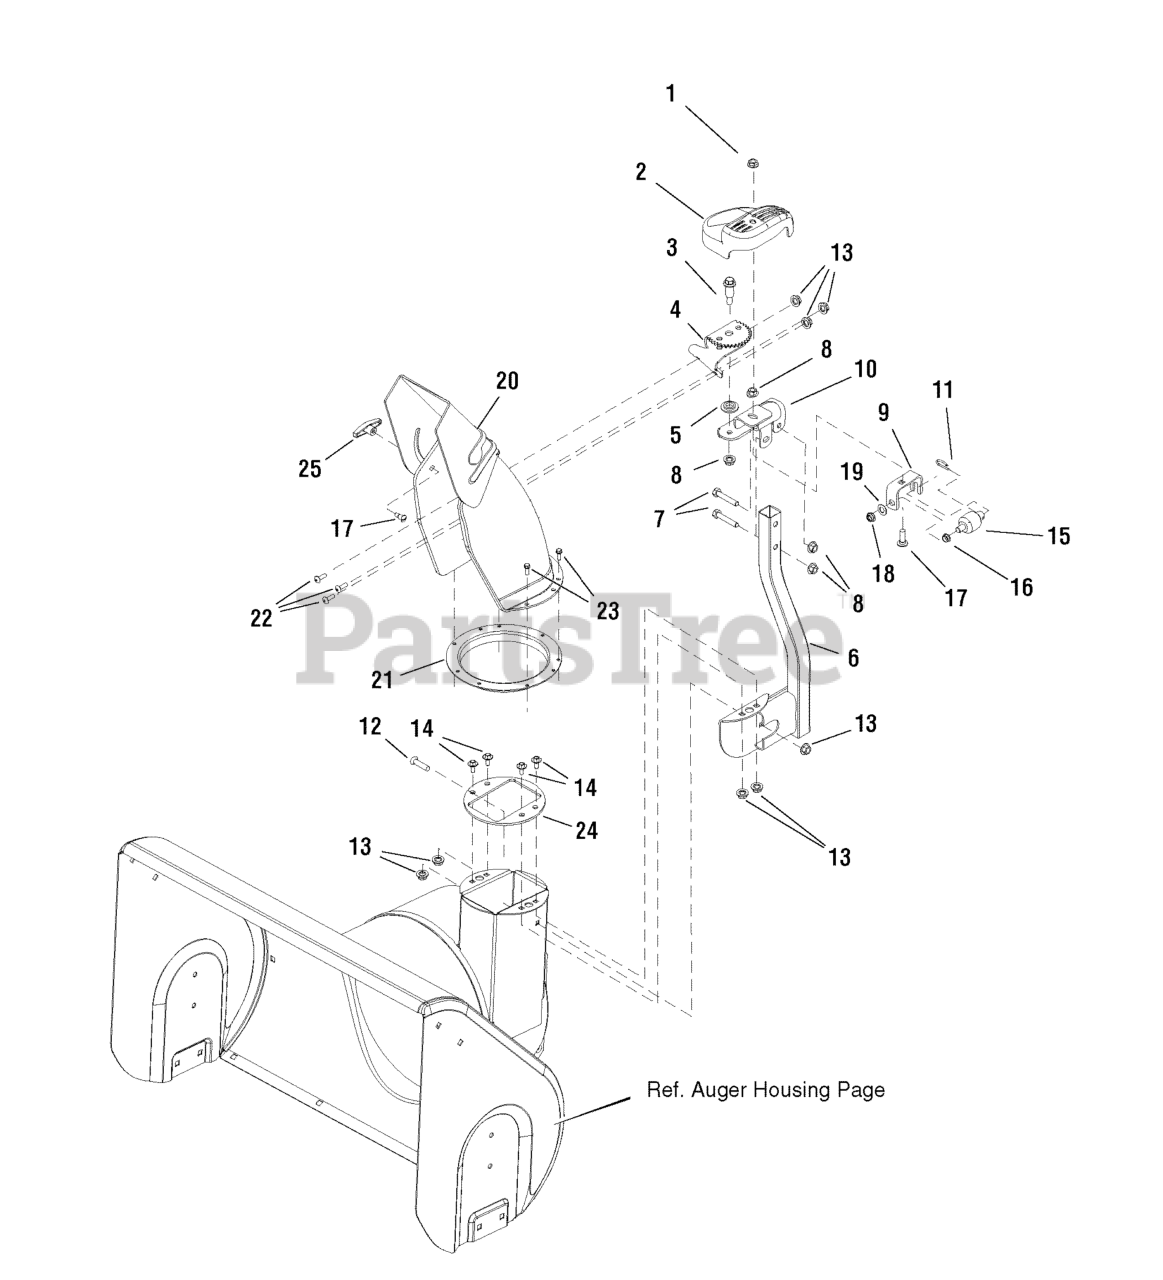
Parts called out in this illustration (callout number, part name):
1	NUT, Hex Flange 5/16-18 Two Way Lock
2	COVER, Gears
3	BOLT, Shoulder 5/16-18 G5
4	GEAR & SUPPORT ASSEMBLY, Chute
5	WASHER, Powdered Metal
6	CHUTE SUPPORT ASSEMBLY
7	SCREW, Hex Head Cap, 5/16-18 x 1 3/4
8	NUT, Hex KEPS 5/16-18 Conical Washer
9	SUPPORT, Worm "U" 10GA
10	SUPPORT, Gear & Chute 10GA
11	PIN, Hair Chute Gear
12	BOLT, CARRIAGE 0.25-20 x 0.75
13	NUT, Nylock Flanged, 1/4-20
14	SCREW, HEX WASHER
15	WORM, Chute L.H.
17	BOLT, 5/16-18 X 1.00
18	NUT, Hex Lock Jam ESNA Lite 3/8-24
19	WASHER, Cup
20	DISCHARGE CHUTE ASSEMBLY
21	CHUTE RING
22	SCREW, Truss Head, 1/4-20 x 3/4
23	CAPSCREW, Hex Head Taptite, 1/4-20 x 1/2
24	GUIDE, CHUTE RING
25	KNOB, WING
